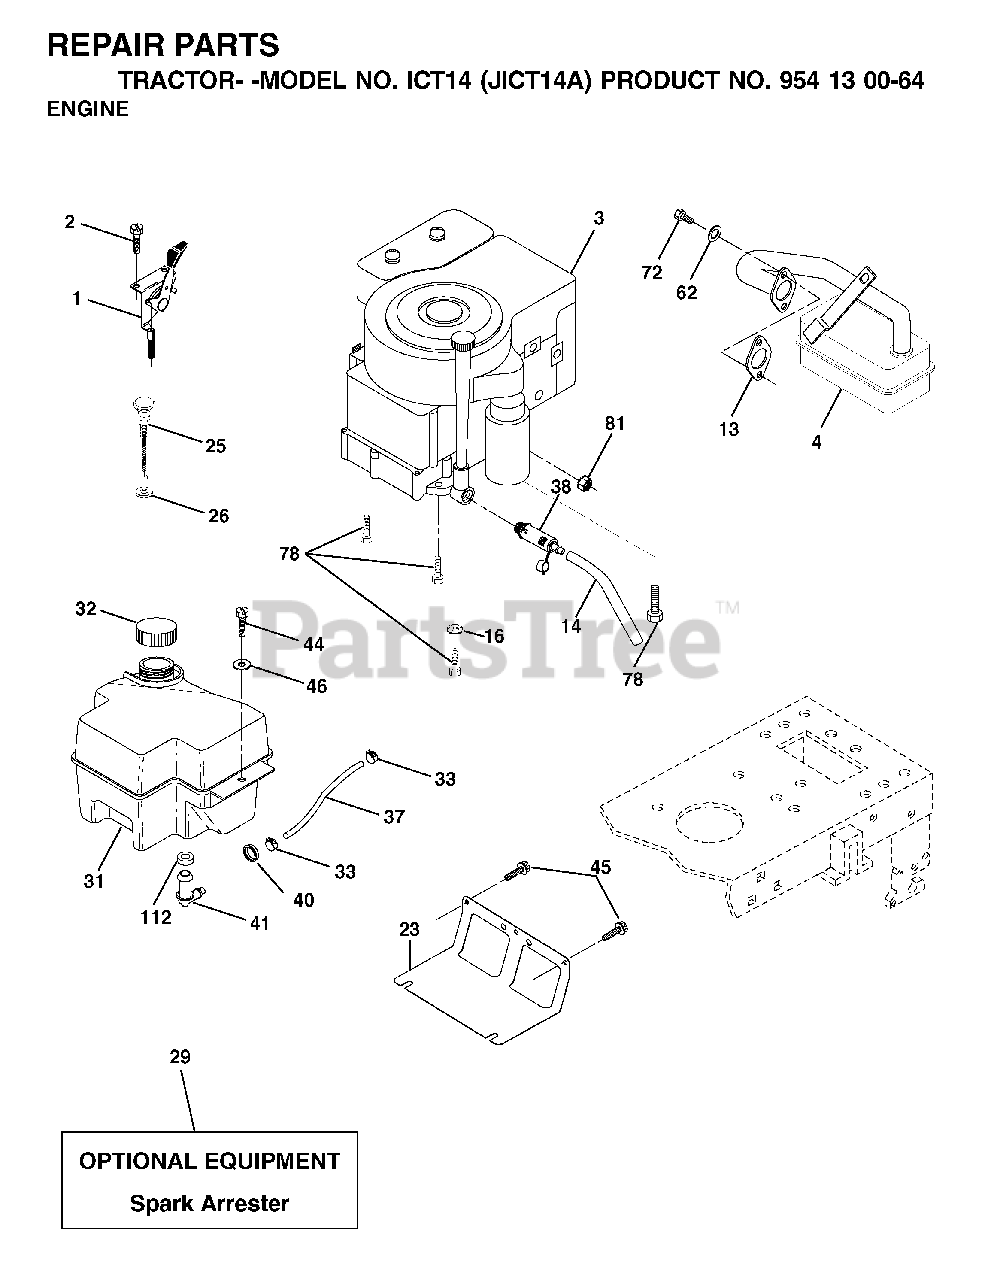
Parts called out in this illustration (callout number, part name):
1	CONTROL TH/CH FLAG
2	SCREW
13	REPL BY 532 27 22-93
14	TUBE, DRAIN OIL ASM.
16	LOCKWASHER
23	SHEILD.BROWNING.DBR.GUARD
26	NUT KEPS 3/8 - 24 UNF
29	ARRESTER SPARK (OPTIONAL)
31	GAS TANK 2GAL
32	FUEL CAP
33	HOSE CLAMP
37	LINE.FUEL.20
38	PLUG, OIL DRAIN EASY
40	GROMMET T
41	STEM FUEL TANK
44	SCREW HEXWSHR 1/4-20X3/4
45	SCREW, 3/8-16X3/4
46	WASHER
62	LOCKWASHER
72	SCREW
78	SCREW.3/8-16
81	NUT
112	BUSHING OUTLET T
